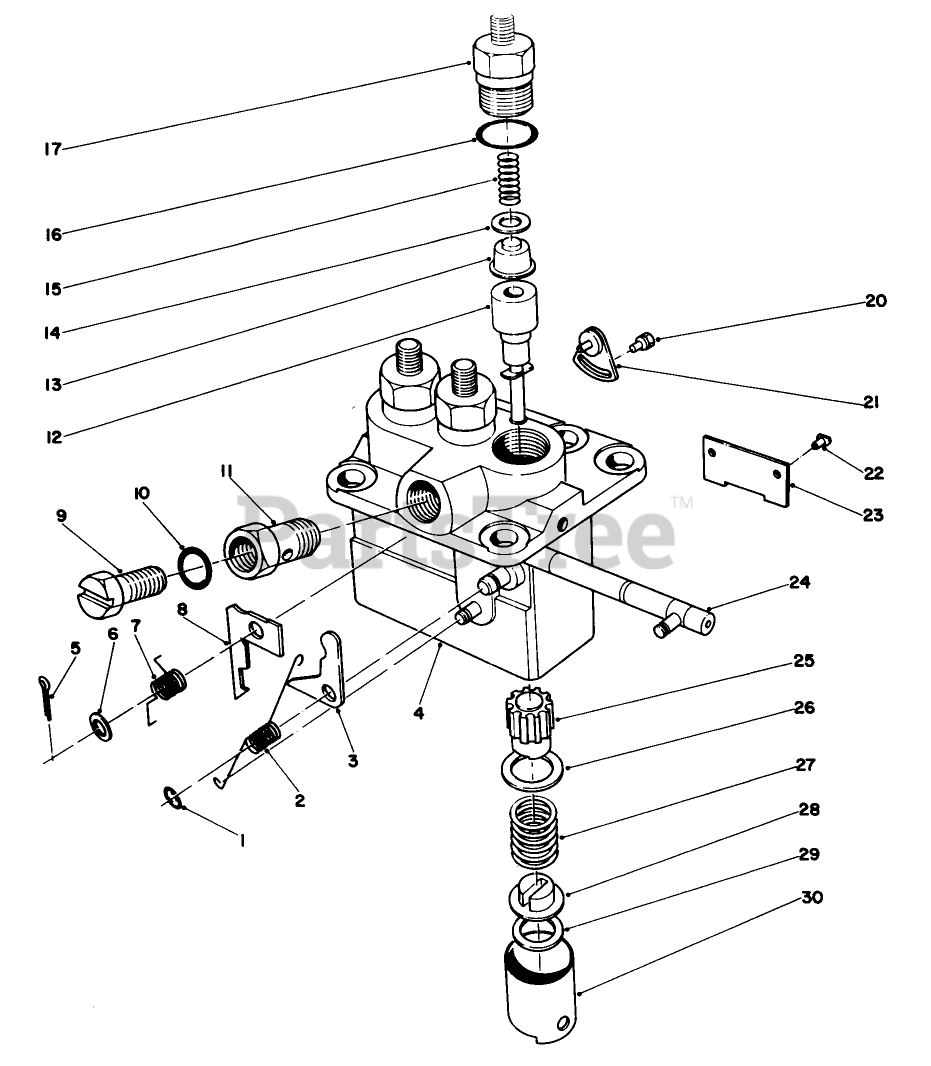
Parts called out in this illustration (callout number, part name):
1	E-Ring
2	SPRING MM 501256
3	ANGLE PLT
4	Housing Sub Assembly Pump
5	Pin, Split
6	Washer, Plate
7	Spring Retum
8	ANGLE PLT
9	Screw-Air Breather
10	WASHER
11	SCREW
12	PUMP ELEMNT
13	VALVE ASM
14	Gasket
15	VALVE SPRNG
16	O-Ring
17	Holder-DeliveryValve
21	ADJ PLT ASM
22	GUIDE PIN
23	PLATE
24	Asm-Rack, Control
25	Sleeve-Plunger Control
26	SPRNG SEAT
27	PLUNGER SPRG
28	SPRING SEAT
29	Plate, .6T
30	Asm-Tappet
